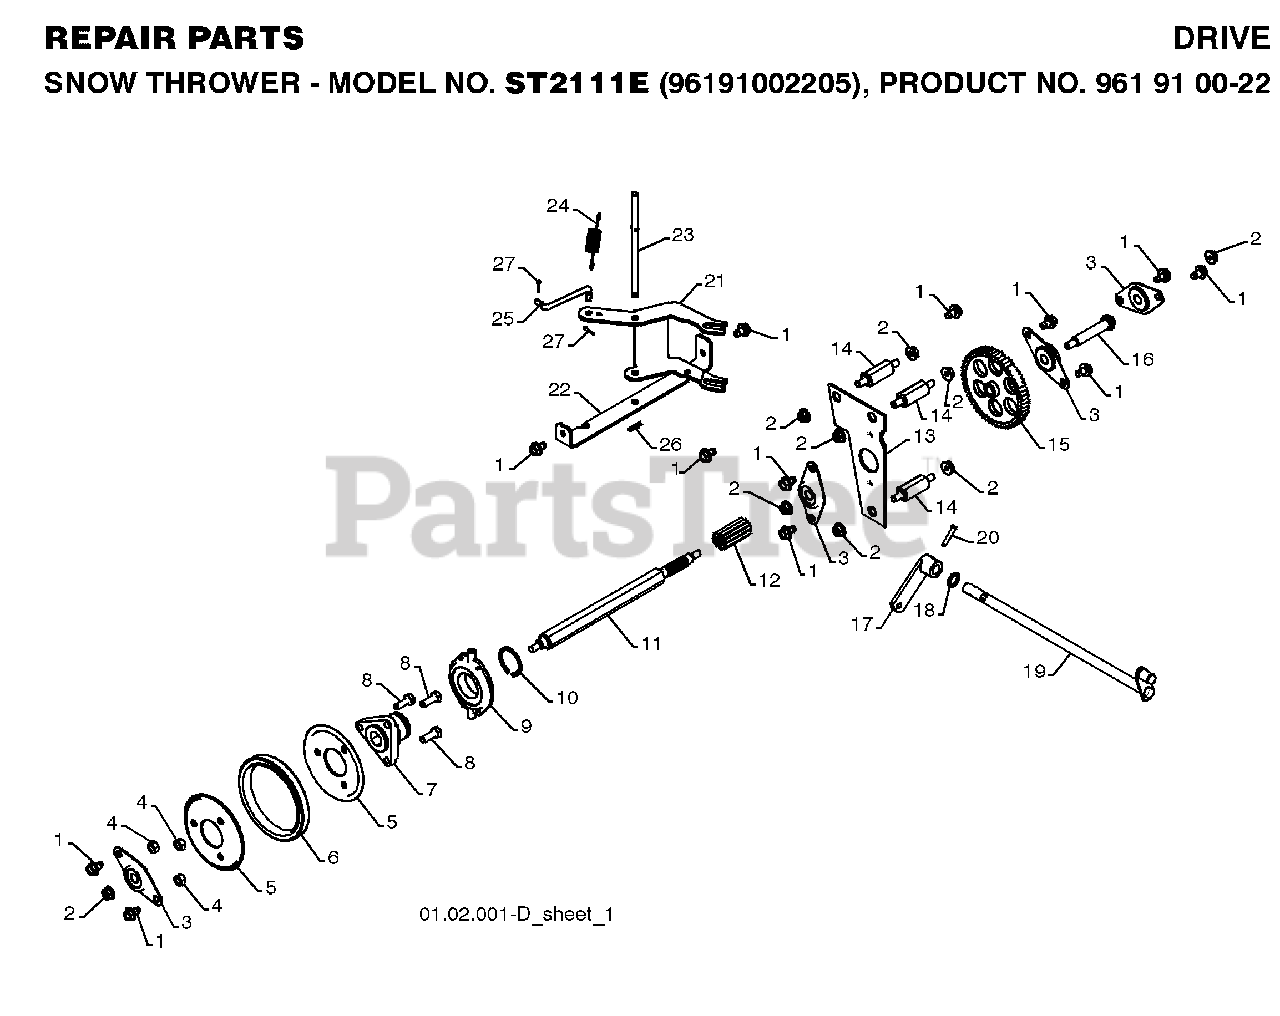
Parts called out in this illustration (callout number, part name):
2	NUT, LOCK 5/16-18
3	BEARING, FLANGE
4	NUT.CENTERLOCK.5/16-
5	PLATE.RUBBER.WHEEL
6	RING, RUBBER WHEEL
7	HUB, RUBBER WHEEL
9	TRUNNION BEARING ASSY
10	RETAINING RING
11	SHAFT.HEX.LONG
12	GEAR, PINION
13	AUXILLARY PLATE
14	SPACER, PLATE
15	GEAR, INTERMEDIATE
16	SHAFT, AUXILIARY
17	ARM, AUGER CONTROL
18	THRUST WASHER
19	SHAFT, AUGER CONTROL
20	CLEVIS PIN
21	LEVER, SPEED CONTROL
22	BRACKET, PIVOT, SHIFT
23	PIN, PIVOT
24	SPRING, BIAS
25	LINK, SPEED CONTROL
26	RETAINER CLIP PM
27	RETAINER CLIP
